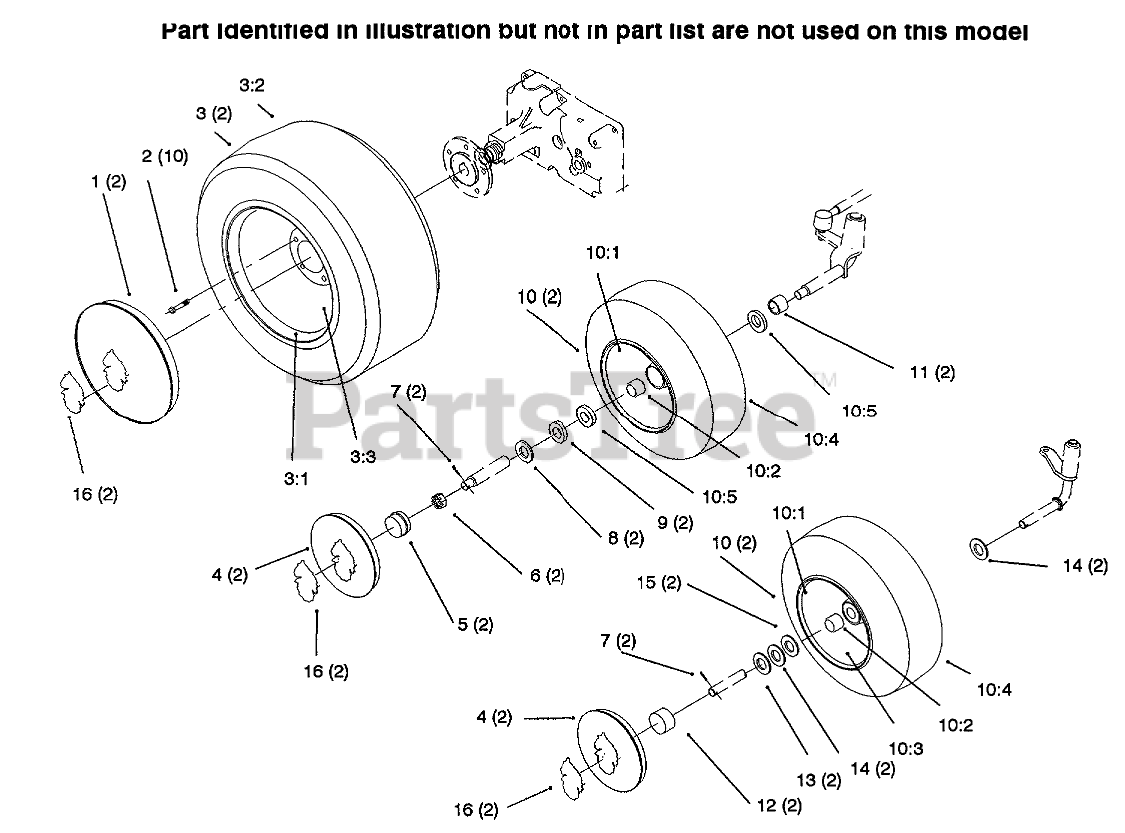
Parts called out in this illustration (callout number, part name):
1	HUBCAP - 12"
2	BOLT-LUG
3	ASM-Wheel& Tire
3:1	WHEEL
3:2	TIRE
3:3	VALVE
4	HUBCAP - 8"
7	PIN-COTTER
10	FRONT WHEEL ASM
10:1	Wheel ASM
10:2	BEARING-WHEEL
10:3	VALVE
10:4	Tire (16 x 6.5-8) 2-Ply -2 Wheel Axel
12	HUBCAP
13	WASHER WHEEL
14	WASHER
15	WASHER-SHIM
16	LOGO (GOLD)
